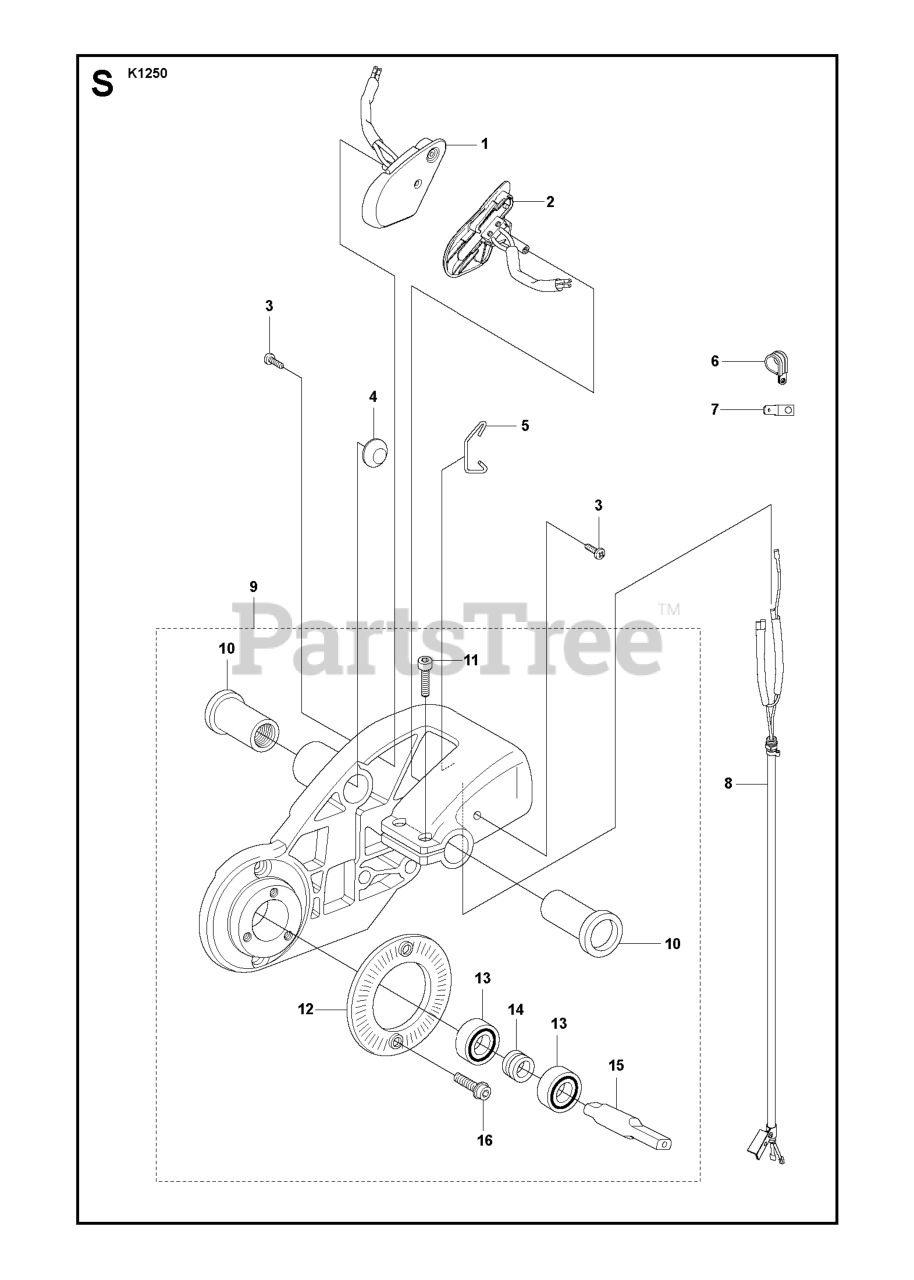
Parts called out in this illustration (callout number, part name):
1	STOP SWITCH RH
2	STOP SWITCH LH
8	CABLE ASSY
9	BEARING HOUSING
13	BALL BEARING
